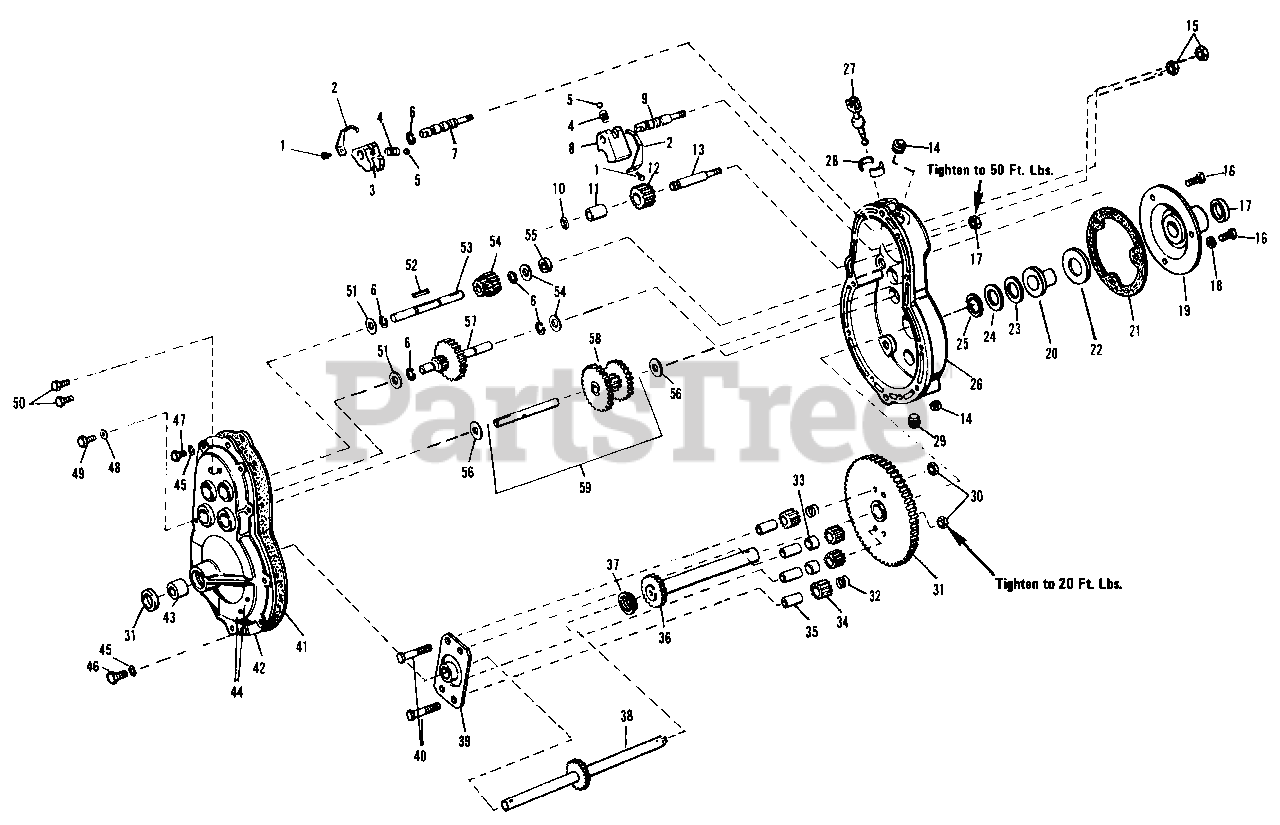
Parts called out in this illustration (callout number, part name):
1	SCREW, Hex Head, 5/16-18 x 5/16
2	SPRING
3	FORK, Shift, Reverse
4	SPRING
5	BALL-shift lock
6	RING-retaining
7	SHAFT, Reverse & I (990776 & 990777 Only)
8	FORK, Shift, I & II (990776 & 990777 Only)
9	SHAFT. Hi-Lo (990776 & 990777 Only)
10	"O" RING
11	BEARING-roller
12	PINION-reverse
13	SHAFT, Reverse, Pinion
14	PLUG-pipe
15	NUT-hex
16	Screw, Cap, Hex., 3/8"-16 N.C. x 7/8" lg.
17	SEAL, Oil (990560 Only)
18	Lockwasher, 3/8" (Mfg. Nos. 920 & 953)
19	PLATE SUPPORT ASSEMBLY
20	Includes: BUSHING
21	GASKET (990560 Only)
23	WASHER (990560 Only)
24	WASHER (990560 Only)
25	RING, Retaining (990560 Only)
26	CASE ASSY., Gear (Includes Ref. Nos. 6, 7, 8, 9, 13 & 14)
27	Includes: SHIFT ROD ASSEMBLY
28	BUSHING, Ball, Half
29	Pipe Plug, 3/8" Std.
30	SCREW, Hex Head, 3/8-16 x 1-1/4
31	GEAR ASSY., Drive
32	SPRING-thrust
33	SPACER-diff.
34	PINION-diff.
35	SPINDLE-pinion diff.
36	AXLE TUBE & BUSHING ASSEMBLY
37	CUP, Thrust (990643 & 990796 Only)
38	AXLE-assembly
39	DIFFERENTIAL PLATE ASSEMBLY
40	Capscrew, Hex Hd., 3/8"-16 NC x 2-1/2" lg.
41	GASKET-case
42	COVER-gearcase sub-assembly
43	Includes: BUSHING
44	Set Screw, Cup Pt. Socket Hd., 3/8"-16 x 3/8"
45	Lockwasher, External 1/4" (Mfg. Nos. 953 & 954)
46	Hex Capscrew, 5/16"-18 x 1-1/2" lg.
47	Hex. Hd. Capscrew, 5/16"-18 N.C. x 1-1/4" lg.
48	Plain Washer, 5/16" (Mfg. Nos. 953 & 954)
49	SCREW, Hex Head, 3/8-16 x 1-1/4
50	Hex Capscrew, 7/16"-14 x 3/4" lg.
51	WASHER
52	KEY
53	SHAFT, Pulley
54	PINION ASSEMBLY hi-lo
55	SEAL-oil
56	WASHER
57	GEAR & SHAFT ASSEMBLY
58	CLUSTER GEAR ASSEMBLY
59	SHAFT & GEAR ASSEMBLY
